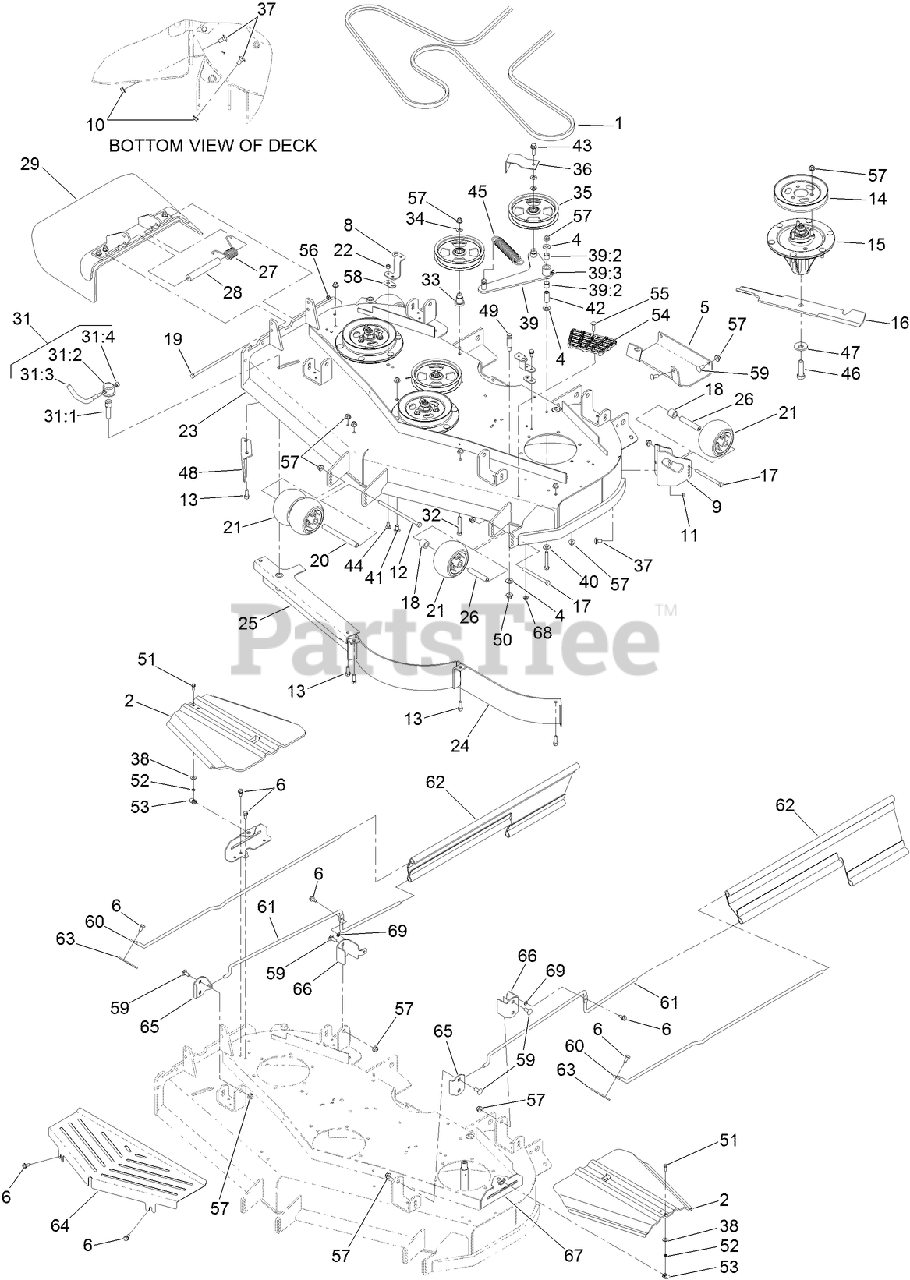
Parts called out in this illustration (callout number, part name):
1	BELT-V
2	COVER-BELT
4	WASHER-FLAT
5	Plate-Skid
6	SCREW-HWHTF
8	BRACKET-COVER, TALL
9	MOUNT-WHEEL, LH
10	NUT-HHF, WHIZ
11	NUT-LOCK, NI
12	SCREW-HH
13	SCREW-HWH
14	PULLEY-B SECTION
15	SPINDLE ASM
16	BLADE-18IN, HI FLOW
17	SCREW-HH
18	TUBE-SPACER
19	SCREW-HH
20	SPACER-WHEEL
21	ROLLER-SCALP, ANTI
22	NUT-LOCK, NI
23	DECK DECAL ASM
26	TUBE-SPANNER
27	SPRING-TORSION
28	SPACER
29	RUBBER DEFLECTOR ASM
31	LEVER ASM
31:1	Screw-Lock
31:2	CAP-LOCK
31:3	Lever-Lock
31:4	NUT-LOCK, NI
32	SCREW-HH
33	MOUNT-PULLEY
34	WASHER-FLAT
35	PULLEY-IDLER, FLAT
36	GUIDE-BELT
37	SCREW-CARR
38	WASHER-THRUST
39	DECK IDLER ARM ASM
39:2	SLEEVE-BEARING
39:3	FITTING-GREASE, 90 DEG
40	WASHER-BELLEVILLE
41	SCREW-CARR
42	BUSHING
43	SCREW-HHF
44	SCREW-CARR
45	SPRING-EXTENSION
46	SCREW-BLADE
47	Washer-Blade Bolt, Heavy
48	BAFFLE-DISCHARGE
49	PIN-THREADED, SPRING ANCHOR
50	NUT-HF
51	SCREW-HWH
52	NUT-RETAINER
54	STEP-DECK
55	SCREW-CARR
56	NUT-LOCK, NI
57	NUT-HF, NI
58	SPACER-BELT COVER
59	SCREW-CARR
60	ROD-SUPPORT, UPPER
61	ROD-SUPPORT, LOWER
62	GUARD-SIDE
63	BRACKET-MOUNTING, UPPER ROD
64	SHIELD-FRONT
65	BRACKET-MOUNTING, FRONT
66	BRACKET-MOUNTING, REAR
67	BRACKET-SUPPORT, SPINDLE COVER
68	NUT-HF, NI
69	NUT-PUSH
